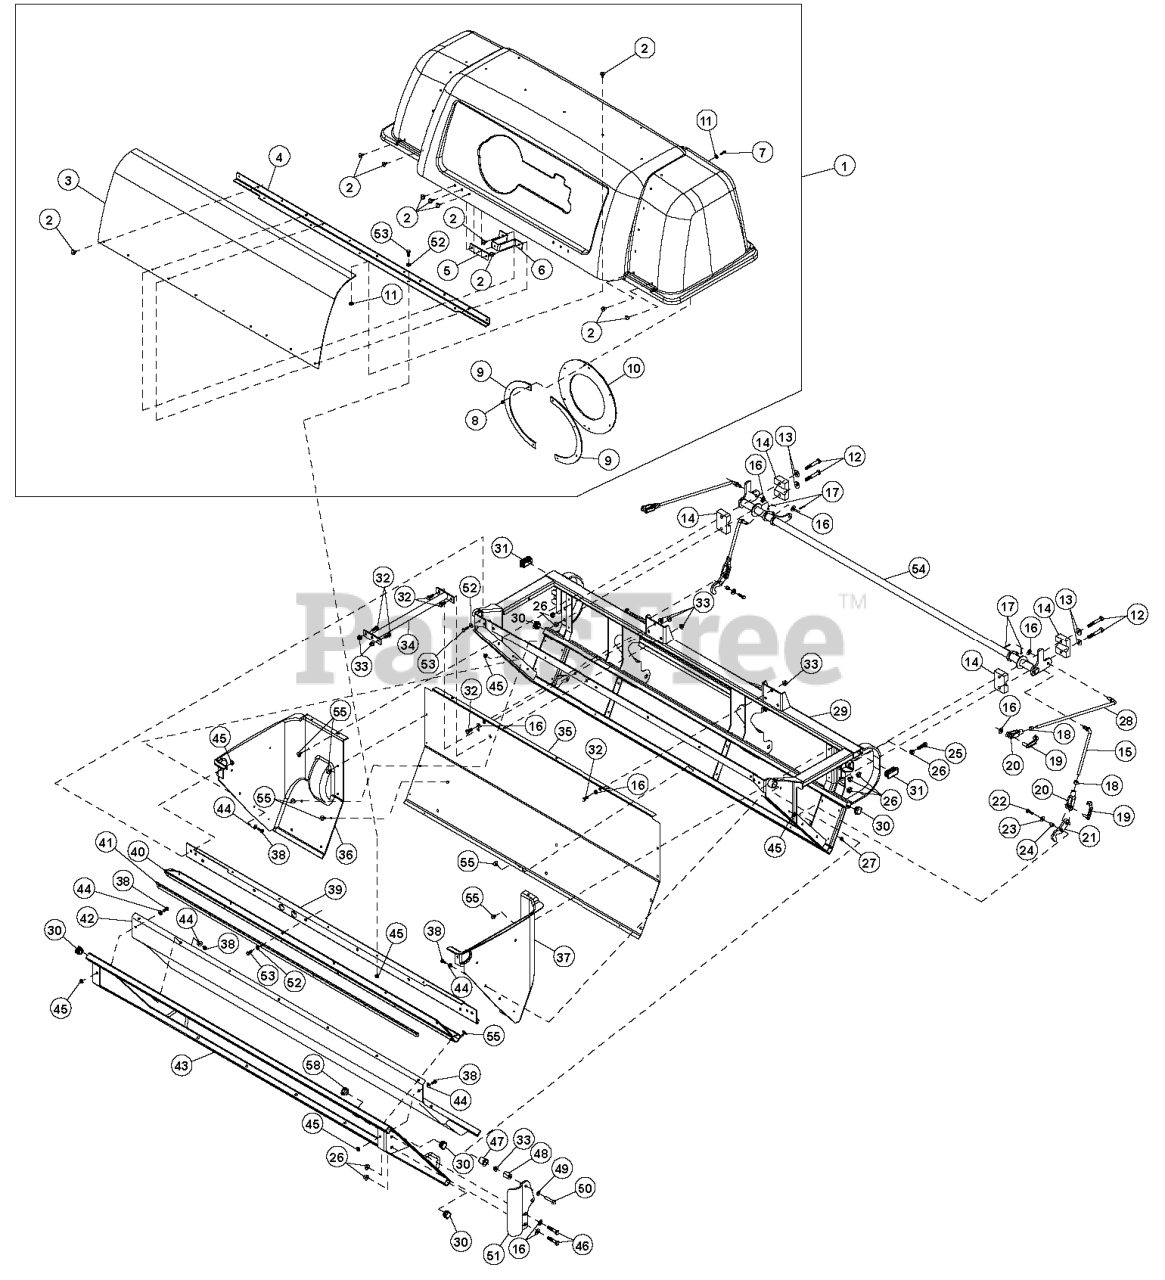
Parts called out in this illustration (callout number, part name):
1:	ASM, HOOD - SERVICE ONLY
2	RIVET-BLIND
3	SCREEN-BAGGER
4	SUPPORT-SCREEN
5	PLATE-LATCH, REINFORCEMEN
6	BRACKET-MOUNT
7	SCREW-PPH
8	NUT-LOCK, NI
9	CLAMP-SEAL
10	SEAL-TUBE
11	WASHER-FLAT
12	BOLT-CARR
13	WASHER-FLAT
15	LINK-HANDLE
16	WASHER-FLAT
17	PIN-COTTER
18	NUT-HEX
19	PIN-SPRING, CLEVIS
20	YOKE-LINKAGE, BRAKE
22	SCREW-HH
23	WASHER-FLAT
25	SCREW-HH
26	NUT-HHF, WHIZ
27	NUT-LOCK, NI
28	LINK-HINGE
29	UPRIGHT-BAGGER
32	SCREW-HH
35	SHEET-WALL
36	PANEL-BAGGER, LH
37	PANEL-BAGGER, RH
38	SCREW-HH
39	REAR CROSSMEMBER ASM
40	SEAL-DOOR HINGE
41	STRAP-HOLD DOWN
42	BAG AND BOTTOM PANEL ASM
43	DOOR ASM
44	WASHER-FLAT
46	SCREW-HH
47	BUSHING
48	PIN-PIVOT, HINGE
49	WASHER-PLAIN
50	SCREW-HH
51	ARM-HINGE, LH
52	WASHER-FLAT
53	SCREW-HH
54	LINK-INTERMEDIATE
55	RIVET-BLIND
58	PLUG-DOME
